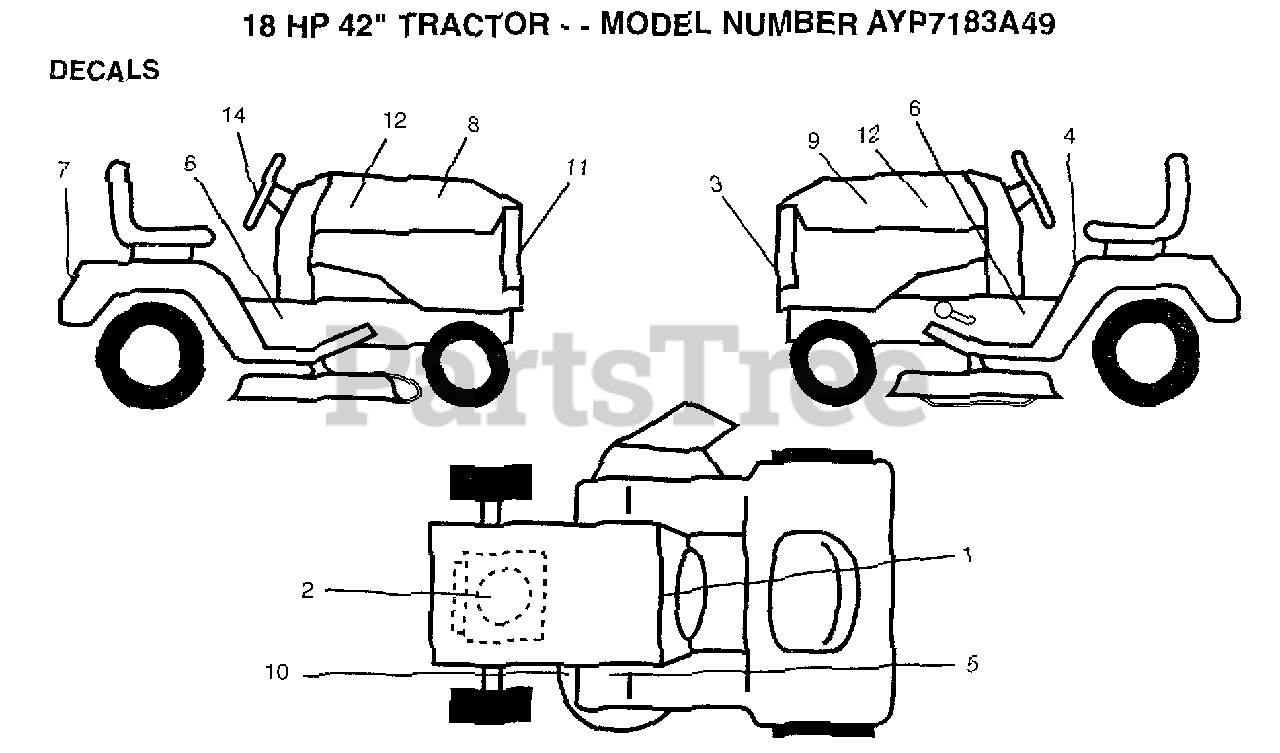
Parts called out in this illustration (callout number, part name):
1	DECAL.DASH.INST.
3	DECAL GRILL WIZ
4	DECAL
6	DECAL CHASSIS WIZ
8	DECAL HOOD RH WIZ
9	DECAL HOOD LH WIZ
10	DECAL
11	DECAL GRILL WIZ
12	DECAL INS HOOD
